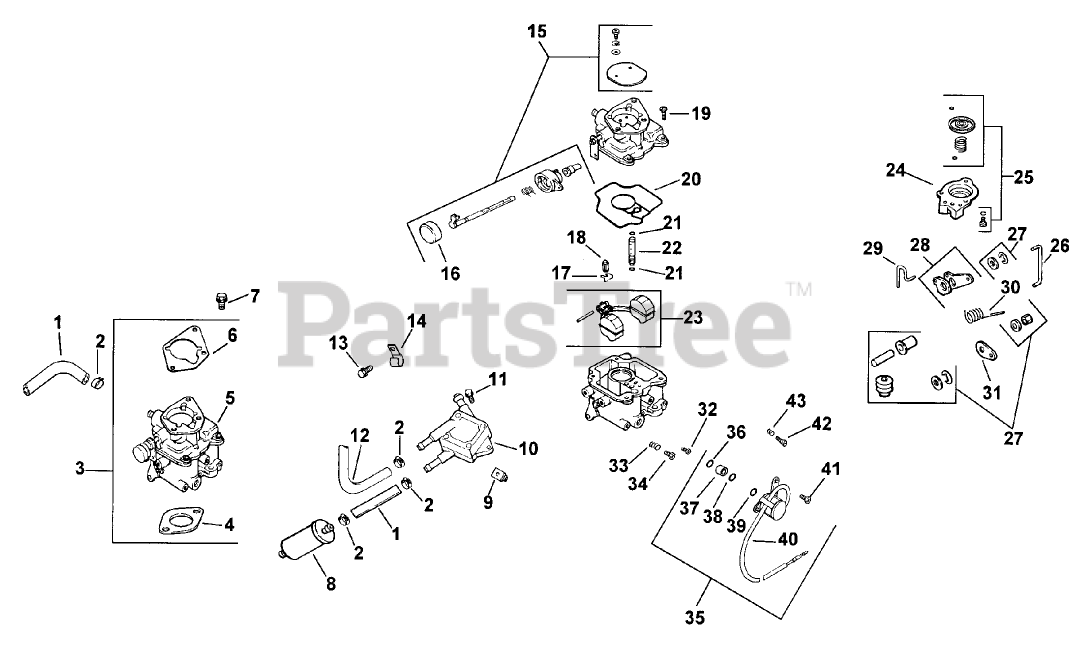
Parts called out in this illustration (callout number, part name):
1	Line fuel
2	Clamp
3	Kit, carburetor w/gasket (Includes 4-6)
4	Gasket
5	Carburetor assembly (Includes 15-43 and carburetor repair kit)
6	Gasket
7	Screw
8	Filter-Fuel
9	Nut
10	Pump-Fuel
11	Screw
12	Line, fuel
13	Screw
14	Clip, cable
15	Kit, choke repair (Includes 16)
16	Cap-Choke Lever
17	Clip, cable
18	Valve-Inlet Needle
19	Screw
20	Gasket-Body,Carburetor
21	"O"Ring
22	Jet-Slow
23	Roat Repair Kit
24	Housing-Pump
25	Kit repair-accelerator pump
26	Linkage-Rod
27	Kit repair-accelerator pump diagram
28	Lever-Rod
29	Linkage-Rod
30	Spring-Linkage
31	Lever-Linkage
32	Jet-Main
33	Spring-Idle Adj.
34	Needle, idle
35	Kit, solenoid assembly (Includes 36-41)
36	O-Ring
37	Seat-Solenoid
38	O-Ring
39	O-Ring
40	Solenoid
41	Screw
42	Screw, idle adjusting
43	Spring-Idle Speed Adj.
